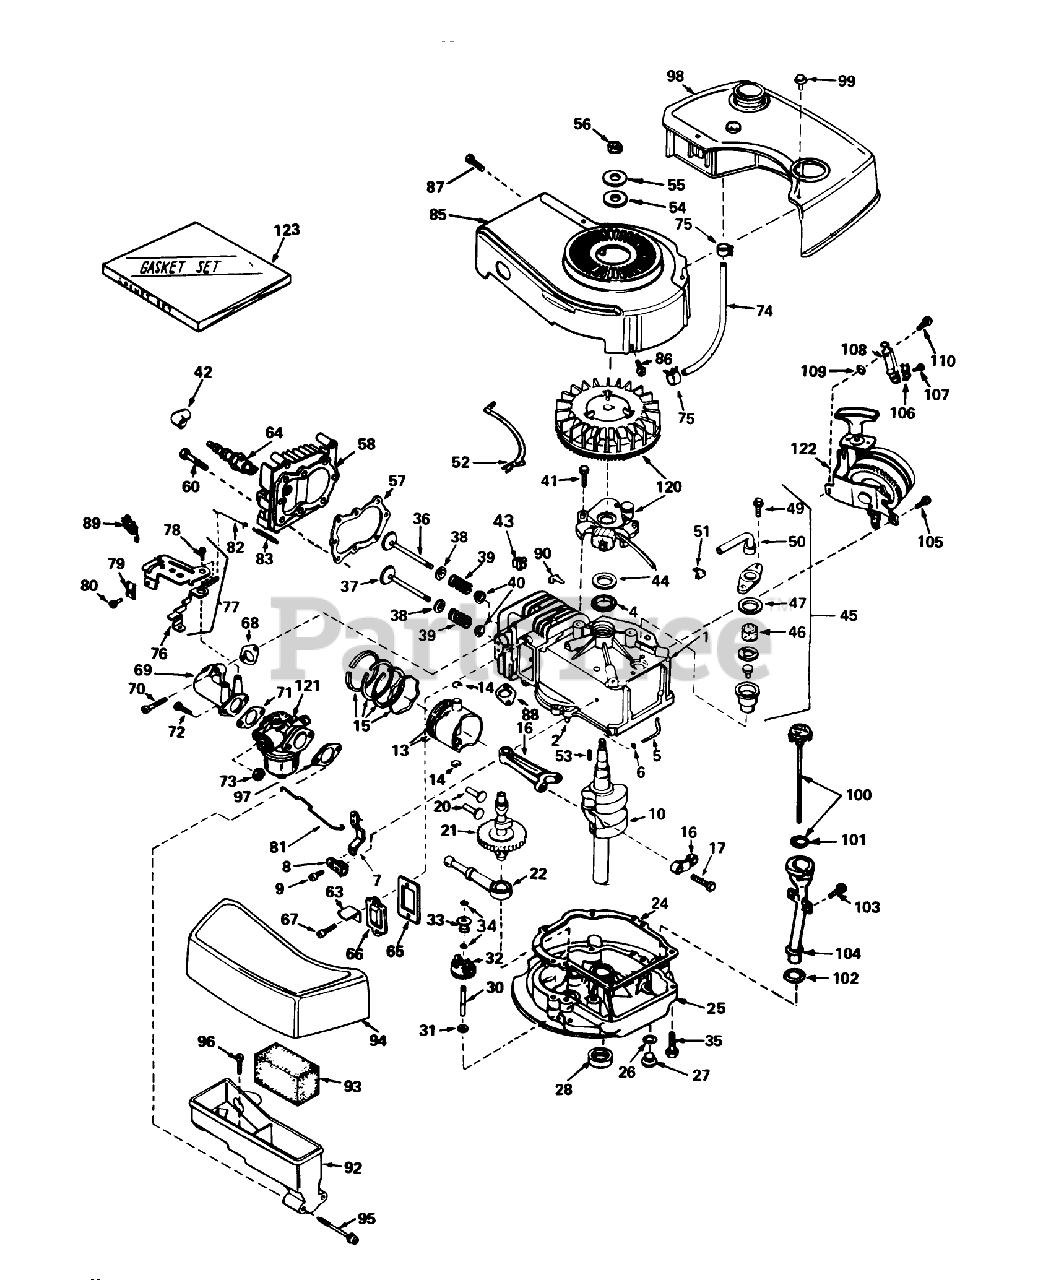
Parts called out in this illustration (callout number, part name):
1	Cylinder Assy. (Incl. Ref. #2, 4 105)
2	Pin-Dowel
4	OIL SEAL
5	Rod, Governor (Incl. No. 36)
6	Washer-Flat
7	Governor Lever
8	Clamp-Lever, Governor
9	Screw
10	Crankshaft
13	Piston, Pin Ring Assy. (Incl.Ref. #14 15)(Std.)
13	Piston, Pin Ring Assy. (Incl. #14 15)(.010 oversize)
13	Piston, Pin Ring Assy. (Incl.Ref. #14 15) (.020 oversize)
14	Ring-Retaining, Piston Pin
15	Ring Set Piston (Std.)
15	Ring Set Piston (.010 Oversize)
15	Ring Set Piston (.020 Oversize)
16	Rod Assy., Connecting (Incl. Ref. #17)
17	Bolt-Rod, Connecting
20	Lifter-Valve
21	Camshaft(Mech.Comp. Release)
22	Oil Pump ASM
24	Gasket, Mounting
25	Flange Assy., Mounting (Incl. Ref. #26thru 30)
26	Gasket-Oil Drain
27	Plug Oil Drain
28	Seal Oil
30	Shaft-Governor
31	Washer-Flat
32	Governor Gear ASM
33	Spool-Governor
34	Ring-Retaining
35	Screw (1/4-20 x 1-1/4)
36	Valve, Intake (Incl. Ref. #38, 39 40) (Std.)
36	Valve, Exhaust (1/32" Oversize) (Incl. Nos. 8, 9 10)
37	Valve, Exhaust (Standard) (Incl. Nos. 8, 9 10)
37	Valve, Exhaust (1/32" Oversize) (Incl. Nos. 8, 9 10)
38	Cap-Upper Valve Spring
39	Spring-Valve
40	Cap-Valve, Spring
41	Screw
42	Cover-Spark Plug
43	51004 GIL ROTARY TI
44	Gasket Stator
45	Breather Assy. (Incl. Ref. #46, 47, 49, 50 51 )
46	Element-Breather
47	Gasket-Breather
49	Screw, Hex Hd. w/Conical
50	Tube, Breaker
51	Clip, Breather
52	Wire Ground
53	Key-Flywheel
54	Washer Flat
55	Washer-Spring
56	Hex Nut
57	63573 GIL 42 SNWTHW
58	Head-Cylinder
60	Screw (5/16-18x1-1/2)
63	Retainer Clip
64	Plug, Spark (J17LM or equiv.)
64	Plug, Spark (Champion RCJ-8)
65	Gasket-Breather
66	Cover-Valve
67	Screw
68	Gasket, Intake
69	Pipe, Intake
70	Screw (1/4-20 x 1)
71	Gasket-Carburetor
73	Nut and Lock Washer (1/4-28)
74	Line-Fuel
75	Clamp-Line, Fuel
76	Lever Control
77	Control Assy., Speed (Incl. Nos, 76, 78 89)
78	Screw, Hex Washer Hd Shoulder Self-Tap
79	Conduit
80	Screw (10-32 x 3/8)
81	Link-Throttle
82	Link Governor Spring
83	Spring Governor
85	Housing, Blower
86	Screw
87	Screw (10-24 x 9/16)
88	Gasket Exhaust
89	Terminal
90	Clip-Wire
92	Body Air Cleaner
93	Filer, Air
94	Cove, Air Cleaner
95	Screw Fil Hd.
96	Screw, Hex Hd.
97	Gasket-Air Cleaner
98	Tank, Fuel
99	Screw (10-32 x 35/64)
100	Dipstick, Oil (Incl. Ref. #101)(Twist Lock)
101	O-Ring
102	Gasket
103	Screw (10-32 x 1/2)
104	Tube-Oil Fill
105	Screw (1/4-20 x 1/2)
106	Conduit
107	Screw (10-32 x 3/8)
108	Bracker
109	Washer
110	Screw (1/4-20 X 5/8)
120	Magneto
121	Carburetor (Incl. Ref. #71 )
122	Starter
123	53024/VAR.16HP O/P
